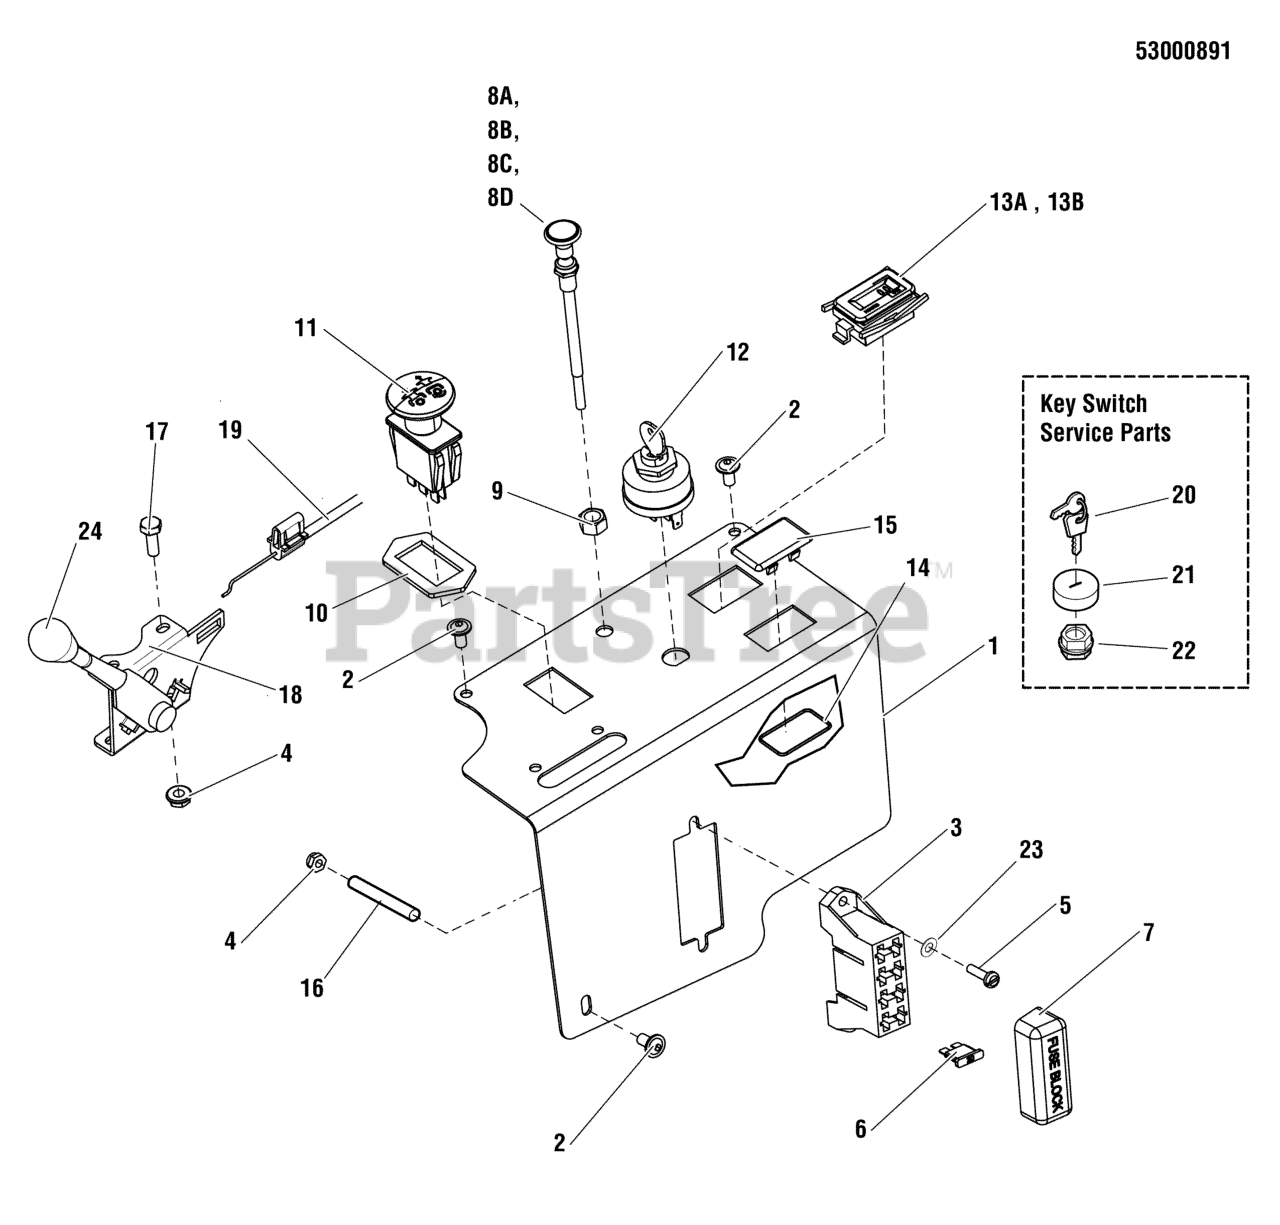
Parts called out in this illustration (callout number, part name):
1	PLATE, CONTROL PANEL, SNP - BLK
2	SCREW, ALLEN HEAD 1/4-20X.500 ZINC PHOS
3	FUSE BLOCK (SV)
4	NUT, #10-24 HEX NYLON LOCK
5	SCREW, #10-24 X 2" ROUND PHILLIPS
6	FUSE, ATP, 20 AMP (SV)
7	COVER, VINYL FUSEBLOCK
9	NUT, 3/8-24 HEX
10	RING, SWITCH RETAINER
11	SWITCH, BLADE ENGAGEMENT
12	SWITCH, IGNITION, 6 POST
14	O-RING, 7/8 ID X 1/16 W
15	PLUG, .820X1.44 HOLE, BLACK PLASTIC
16	SPACER, .20 X .38 X 1.25
17	SCREW, 10-24 X 3/4
18	LEVER, THROTTLE CONTROL, HEAVY-DUTY
19	CABLE, THROTTLE, 42"
20	KEY, IGNITION MOLDED SET
21	COVER, PLASTIC, SNAP ON
22	PLASTIC NUT
23	WASHER, #10 SAE
24	THROTTLE CONTROL HANDLE/KNOB
